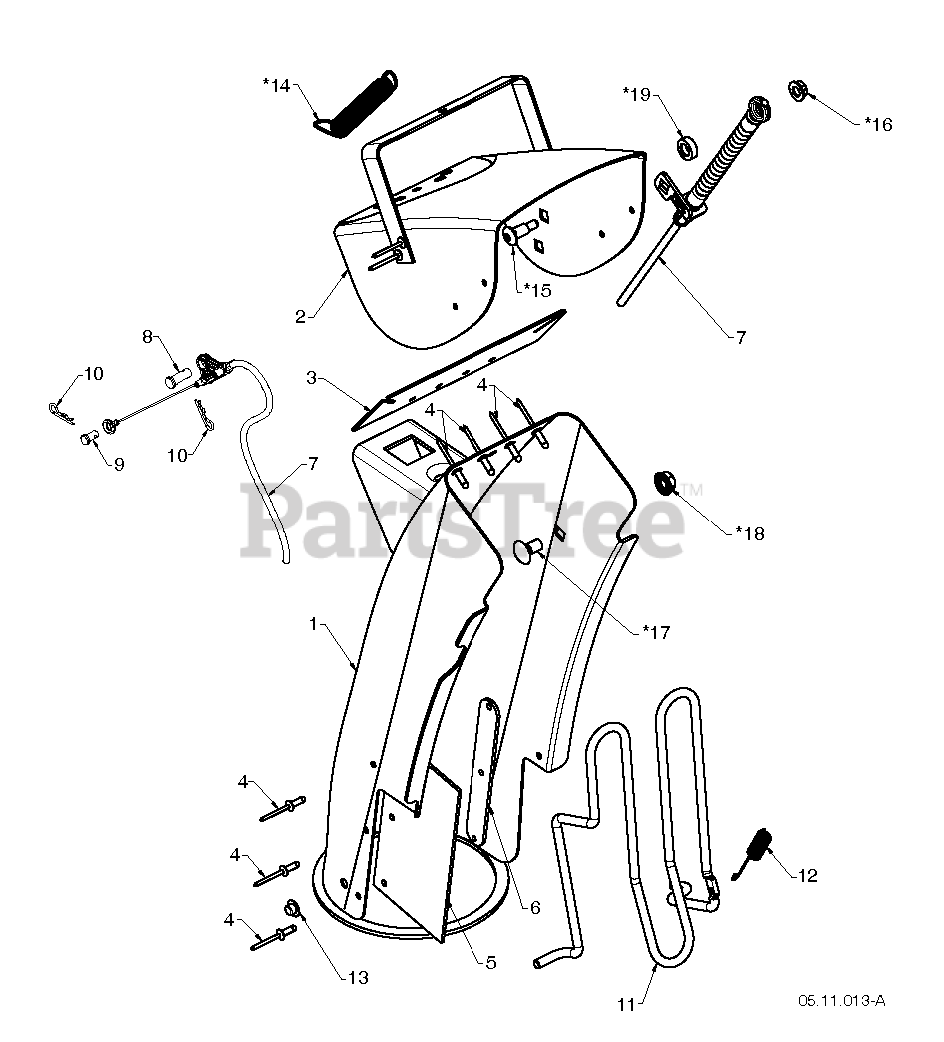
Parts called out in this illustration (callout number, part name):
1	ASM.CHUTE/DEFLECTOR.668
1	BELT WRAPPED IMPELLER -
2	V-BELT.TRACTION.HYDRO
3	ARM.IDLER BRAKE.CLEAR.ZINC
4	PULLEY.W/SPACER.2.75
5	BRACKET.IDLER.PIVOT.ZINC
6	NUT.FLANGE.HEX.5/16X18.BLACK
7	HEX BOLT
8	PIN CLEVIS 5/16X.875
8	BOLT.SHOULDER.1/2X12
9	PIN CLEVIS .25 X .31
9	BOLT.5/16HEX.WHS.HD
10	HAIRPIN.SOFT.ZINC.059X1.125
10	NUT.LOCK.5/16-18
11	GUARD ROD CHUTE GUARD SHORT CL
11	ARM.ASM.TRACTION.IDLER.
12	SPRING.CHUTE.GUARD
12	SCREW, HEX HD 3/8-24 X 1-3/8
13	NUT
13	STEEL WASHER
14	WASHER, FLAT 3/8
15	PULLEY.IMPELER.
16	PULLEY,ENGINE TRACTION DRIVE
17	CAPSCREW.HEXHD.5/16X1.25.
18	WASHER.LOCK.HVY.HLCL.SPR.5/16
19	GUIDE BELT HYDRO LS
20	WASHER.20X8.5
21	RP BUSHING, IDLER PIVOT
22	SPACER.ENGINE.PULLEY
